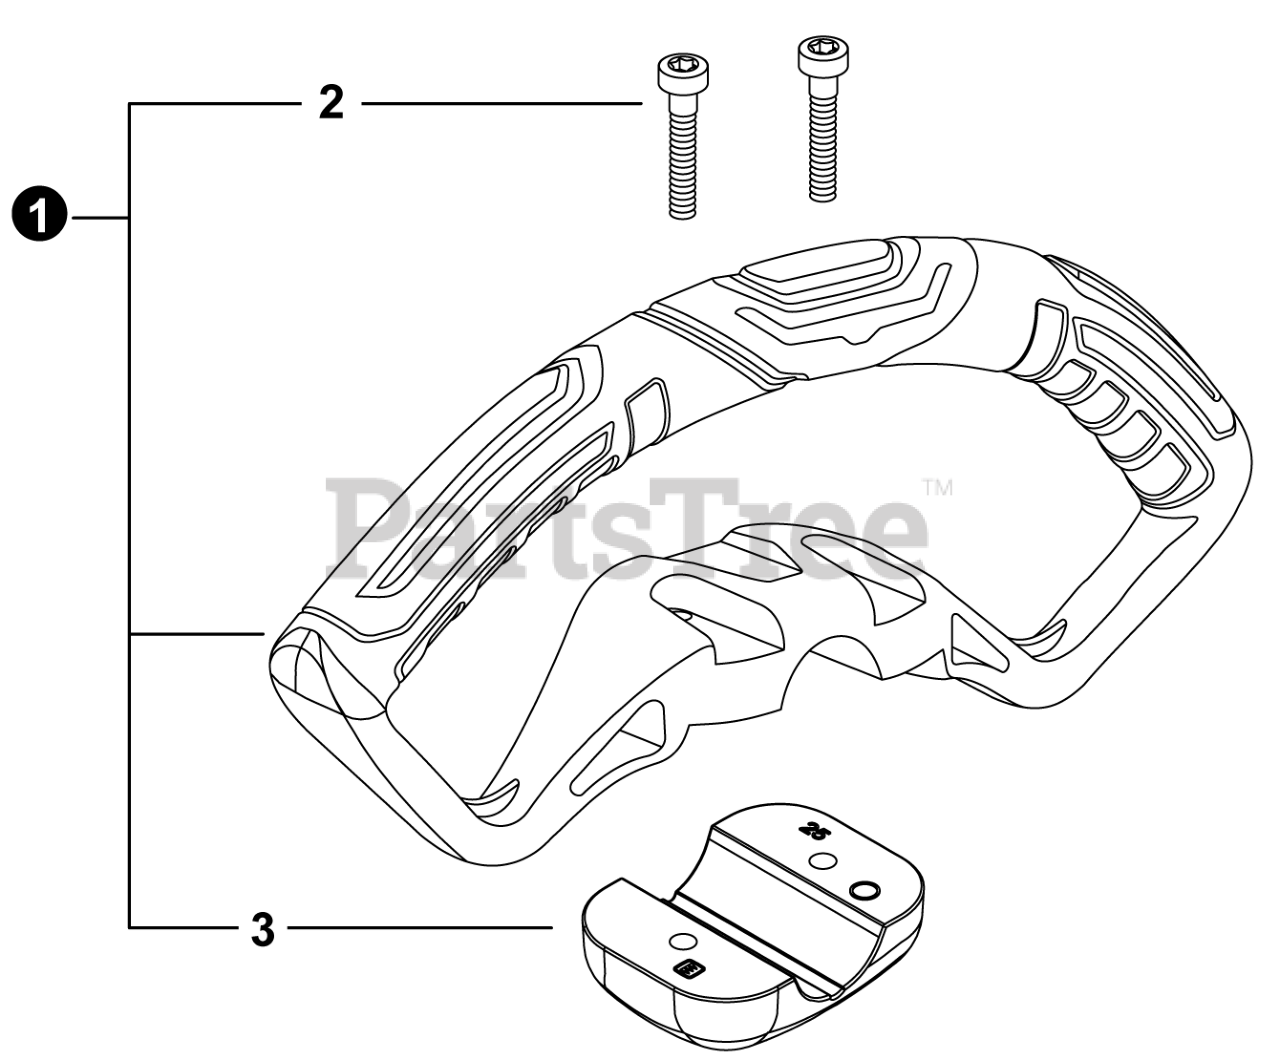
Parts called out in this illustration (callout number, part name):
1	HANDLE ASSY, SUPPORT
2	BOLT, TORX 5x30
3	BRACKET, HANDLE
